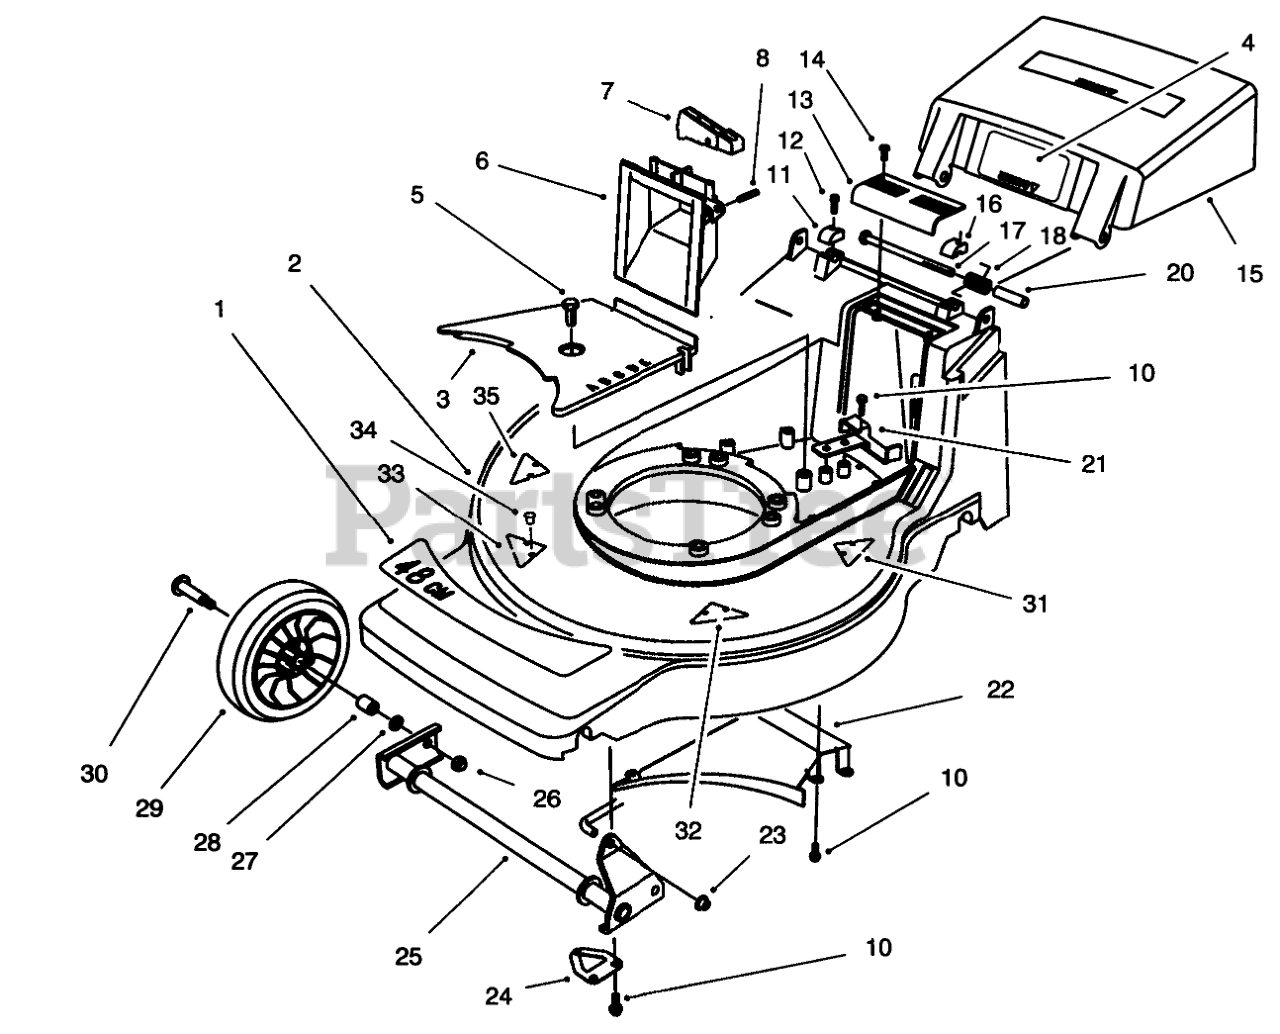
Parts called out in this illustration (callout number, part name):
1	DECAL - DECK
2	Housing-48cm (Incl. Ref. #31-35)
3	BELT COVER
4	DECAL-DANGER
5	SCREW-HWHTF
6	GRIP - LOWER
7	TRIGGER - HOC
8	PIN-SPIRAL
10	SCREW-HWH
11	CAP-HINGE BOLT, RH
12	SCREW-HSH
13	GRIP-UPPER
14	SCREW-PPH, PLASTITE
15	Door Discharge
16	CAP-HINGE BOLT, LH
17	SCREW-HH
18	SPRING-DOOR
20	SPACER-DOOR
21	REAR BELT GUIDE
22	Ramp-Discharge
23	NUT-PUSH
24	SHAFT RETAINER ASM
25	FRONT PIVOT WA
26	NUT-HEX
27	WASHER
28	BUSHING
29	Wheel & Tire Assembly (Incl. Ref. #28)
30	BOLT-WHEEL
31	KICKER
32	KICKER
33	KICKER
34	SCREW-PPH
35	KICKER
